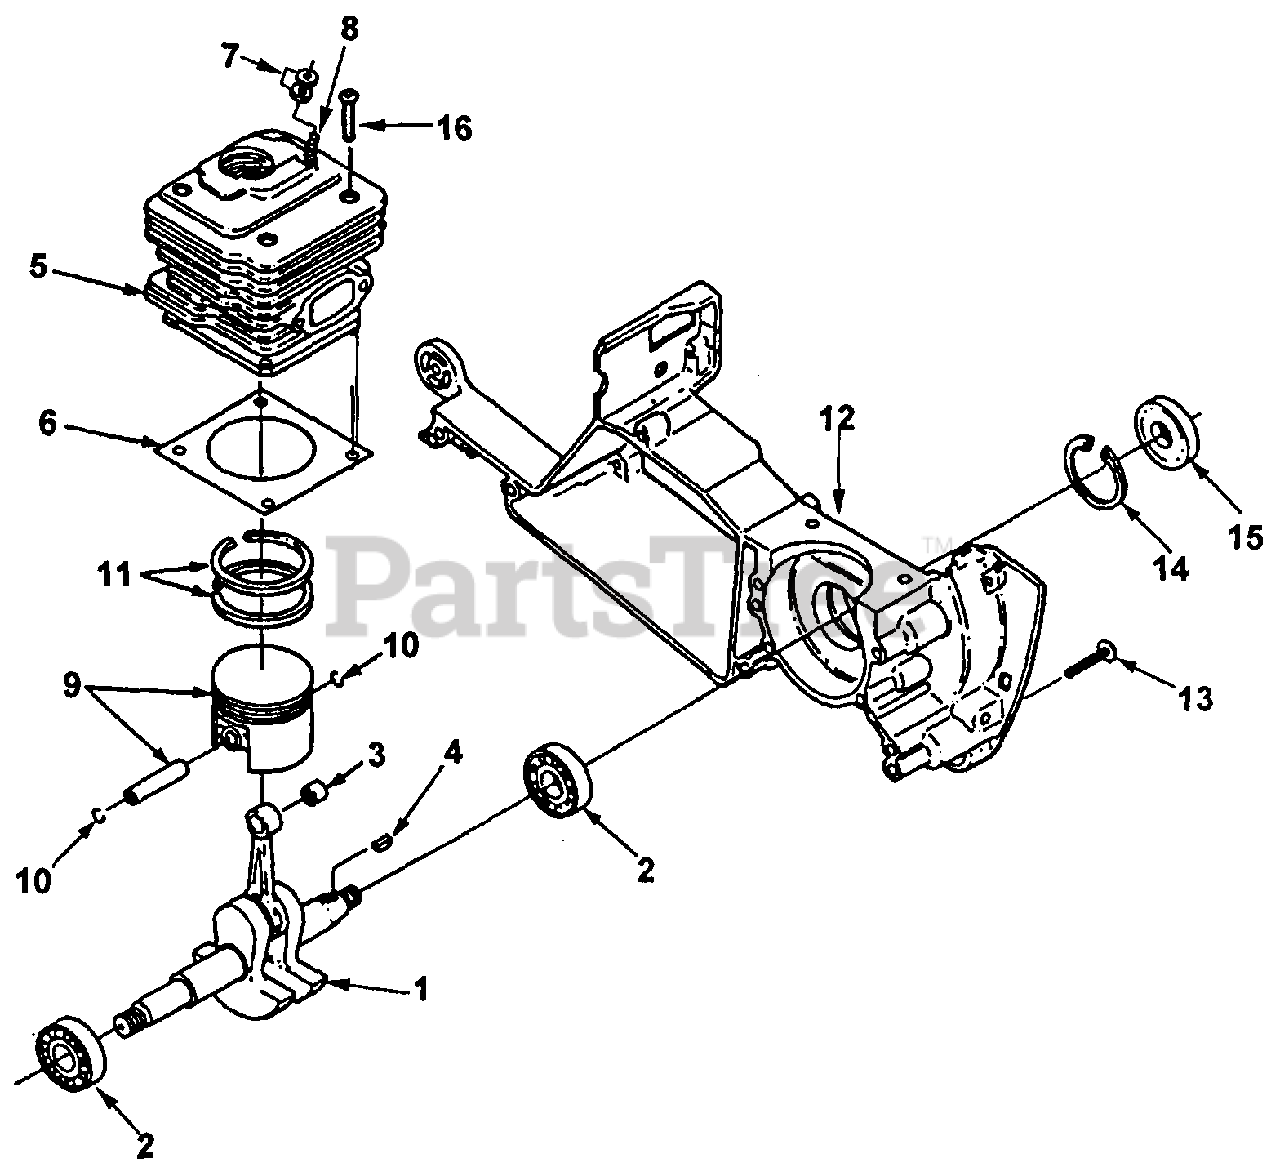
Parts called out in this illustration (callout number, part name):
1	CRANKSHAFT
2	BEARING-Ball
3	BEARING-Piston Pin
4	KEY-Woodruff
5	CYLINDER & PISTON ASSEMBLY
6	GASKET-Cylinder
8	STUD-(10-24 X 1 1/4")
9	PISTON (1.890 Dia.)
10	RING-Retaining
11	RING-Piston
12	CRANKCASE
13	SCREW-Truss Hd. (10-24 X 1 1/4")
14	RETAINER-Bearing
15	SEAL-Main
16	SCREW-Pan Hd (12-24 x 3/4")
